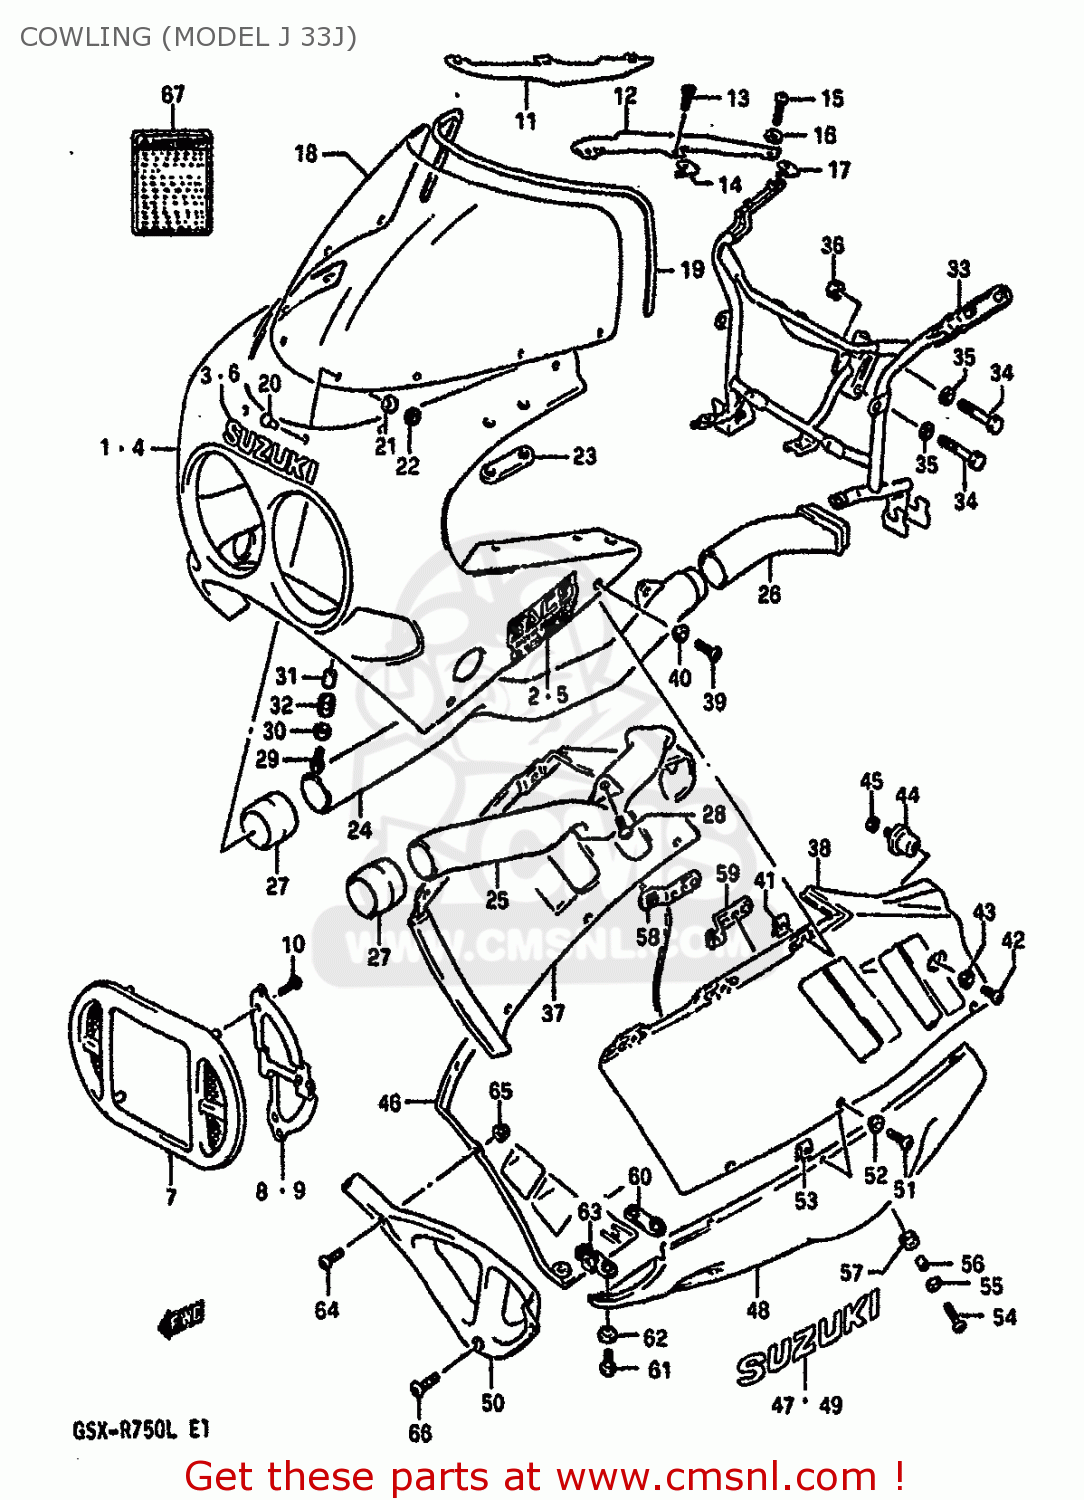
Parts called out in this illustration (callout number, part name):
1	BODY ASSY,COWLING (BLACK)
2	EMBLEM
3	EMBLEM,LEG SHIELD
4	BODY ASSY,COWLING (BLACK)
5	EMBLEM
6	EMBLEM,LEG SHIELD
7	COVER,FRONT (BLACK)
8	PLATE,COVER RH
9	PLATE,COVER LH
10	TAPPING SCREW 4X10/A
11	PANEL,COWLING UPPER,RIGHT
12	COVER,COWLING,LEFT
13	SCREW(5X10)
14	NUT
15	SCREW(5X14)
16	WASHER(5.2X11X1)
17	NUT
18	WINDSCREEN
19	MOLDING
20	PIN,WINDSCREEN
21	CUSHION
22	NUT
23	CUSHION,RR VIEW MIRRORR
24	PIPE,AIR INTAKE,FRONT
25	PIPE,AIR INTAKE,FRONT
26	PIPE,AIR INTAKE RR,R
27	JOINT,AIR INTAKE
28	SCREW
29	SCREW(6X20)
30	WASHER(6.5X18X1)
31	SPACER
32	CUSHION
33	BRACE,COWLING
34	BOLT
35	WASHER,LOCK,8.
36	NUT ,8MM
37	COVER,SIDE RH (BLACK)
38	COVER,SIDE LH (BLACK)
39	SCREW(5X18)
40	WASHER(5.2X14X1.5)
41	NUT,HEADLAMP HOUSING,UPPER
42	SCREW(6X12)
43	WASHER(6.3X16X1.5)
44	CUSHION,COWLING
45	WASHER,LOCK
46	COWLING,UNDER RH (BLACK)
47	EMBLEM
48	COWLING,UNDER LH (BLACK)
49	EMBLEM
50	COWLING,UNDER,CENTER
51	SCREW(5X18)
52	WASHER(5.2X14X1.5)
53	NUT,HEADLAMP HOUSING,UPPER
54	SCREW(6X20)
55	WASHER(6.5X18X1)
56	SPACER
57	CUSHION
58	BRACKET
59	BRACE,COWLING UNDER,LH
60	BRACE,COWLING LWR COVER RR
61	SCREW(6X16)
62	WASHER(6.3X16X1.5)
63	BRACE,COWLING LWR COVER
64	SCREW(5X14)
65	NUT
66	SCREW(6X16)
67	LABEL (WARNING SCREEN)
